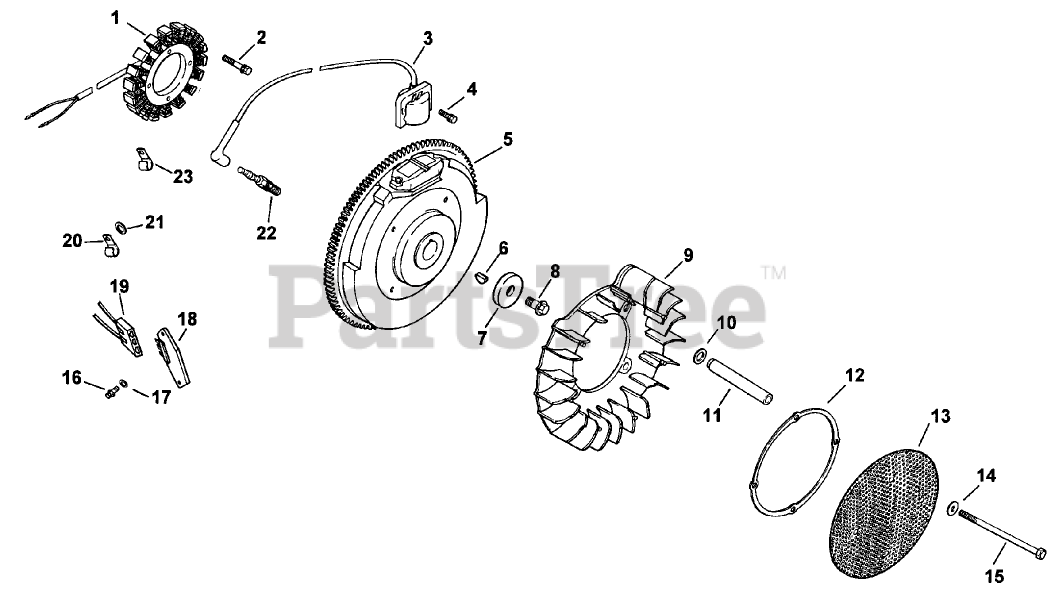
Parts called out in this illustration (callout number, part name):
1	Stator-15 amp
2	Screw
3	Module-Ignition
4	Screw
5	Flywheel
6	Key
7	Washer
8	Screw
9	Fan
10	Washer, sping
11	Spacer
12	Ring-Support
13	Screen-Grass
14	Washer
15	Screw-Hex
16	Screw
17	Washer
18	Rectifier-Regulator
19	Connector
20	Clip
21	Washer
22	Plug-Spark
23	Clip
